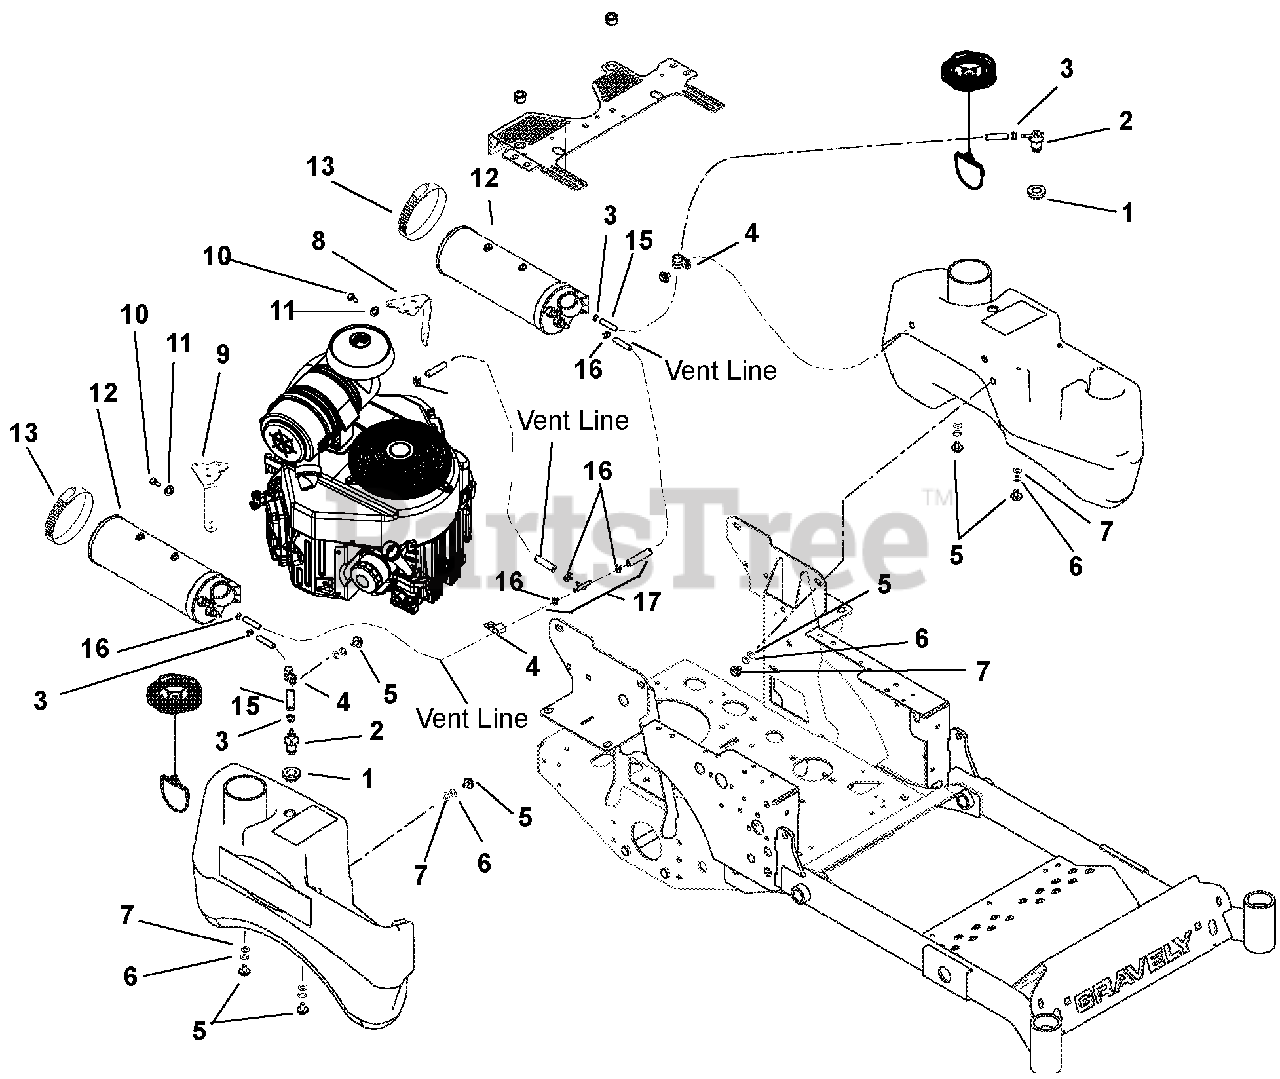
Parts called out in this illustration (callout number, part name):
2	Valve
3	Hose, Clamp
5	Bolt, .31-18 x .62
6	Washer, Locking .31 x .078 Regular
7	Washer, Flat Steel .38 x .875 x .083
8	Bracket, CE Canister Mounting Left Hand
9	Bracket, CE Canister Mounting Right Hand
10	Bolt, Hex M8-1.25 x 20mm
11	Washer, Lock.31 x .078 Reg
12	Canister, Carbon 400 cc CARB
13	Clamp, Hose 2.3/3.2 SS #44
14	T-Clip .38-.50
15	Hose, .25 Low-PERM Bulk Gas 21.0"
16	Clamp, Hose Spring .188
17	Assembly, Compact Pro Vapor CARB
